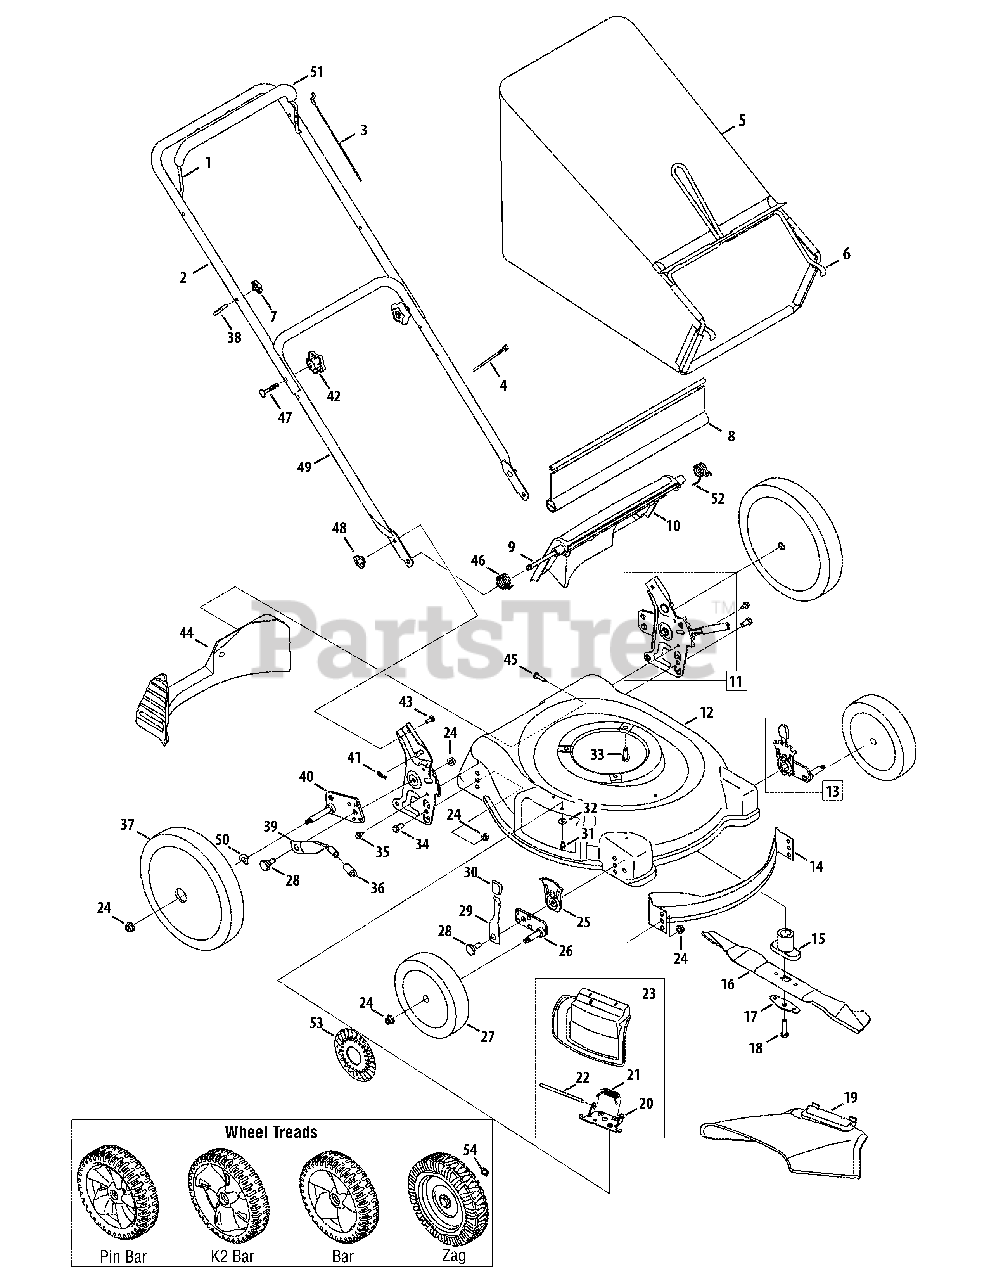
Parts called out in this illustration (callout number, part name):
3	Control Cable, 40"
4	Cable Tie
5	Grass Bag Assembly
5	Grass Bag Assembly w/o Logo
7	Handle Knob
8	Trailshield
9	Pivot Rod
10	Rear Discharge Door
11	Rear Handle Bracket Assy. - LH
11	Rear Handle Bracket Assy. - RH
13	Front Hgt. Adj. Assy., 8" Whl. - RH
13	Front Hgt. Adj. Assy., 7" Whl. - LH
13	Front Hgt. Adj. Assy., 7" Whl. - RH
14	Front Baffle
15	Blade Adapter - 25mm
16	21-inch Mulching Blade
17	Bell Blade Support
18	Hex Screw, 3/8-24 x 2.5
19	Side Discharge Chute
20	Deflector Chute Adaptor
21	Torsion Spring
22	Hinge Pin
23	Mulch Plug Assembly
24	Flange Lock Nut 3/8-16
25	Height Adjustment Plate
26	Pivot Arm Assy LH (7" wheel)
26	Pivot Arm Assy RH (7" wheel)
26	Pivot Arm Assy RH (8" wheel)
26	Pivot Arm Assy LH (8" wheel)
27	Front Wheel, 8 x 1.8, K2 Bar
27	Front Wheel, 7 x 1.8, Bar
27	Front Wheel, 8 x 1.8, Bar
27	Front Wheel, 8 x 2.125, Zag
27	Front Wheel, 8 x 2.125, Zag, Yellow
27	Front Wheel, 8 x 1.8, Pin Bar
28	Shoulder Scr., .5D x .385
29	Front Spring Lever
30	Height Adjust Knob
31	TT Screw, 1/4-20 x .500
32	Bell Washer
33	TT Screw, 3/8-16 x 1.0
34	Hex Screw, 3/8-16 x .75
35	TT Screw, 1/4-20 x .625
36	Foam Grip
37	Rear Wheel, 12 x 1.8, K2 Bar
37	Rear Wheel, 12 x 1.8, Bar
37	Rear Wheel, 12 x 2.125, Zag
37	Rear Wheel, 12 x 2.125, Zag,Yellow
37	Rear Wheel, 12 x 1.8, Pin Bar
38	Eye Bolt
39	Rear Hi-Wheel Spring Lever
40	Rear Pivot Arm Assy - RH
40	Rear Pivot Arm Assy - LH
41	Hairpin Clip
42	Star Knob
43	Carriage Bolt ,1/4-20 x .75
44	Rear Baffle
45	Screw HL, 1/4-15 x 1.00
46	Torsion Spring - RH
47	Carriage Bolt, 5/16-18 x 2
48	Wing Nut
50	Spring Washer
51	Deluxe Bail Cover
51	Deluxe Bail Cover - Red
51	Deluxe Bail Cover - Gray
52	Torsion Spring - LH
53	Hub Cap
54	Wave Washer, .510 x .750 x .017
